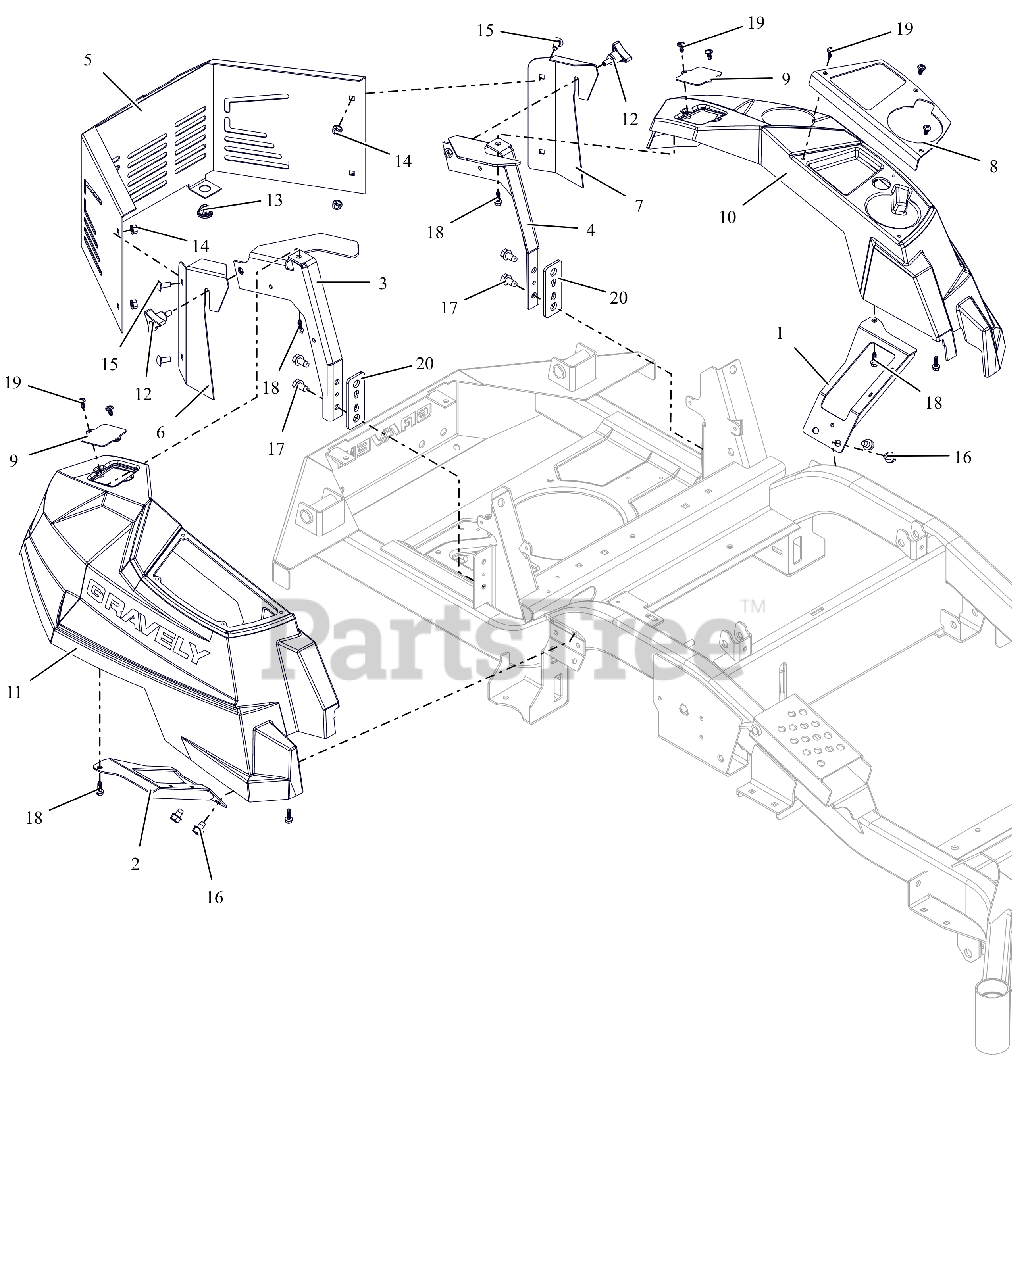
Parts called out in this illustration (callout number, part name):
1	WLDMT, LH FENDER MOUNT
2	WLDMT, RH FENDER MOUNT
3	BRKT, RH FENDER MTG
4	BRKT, LH FENDER MTG
5	GUARD, HD ENGINE
6	TRIM, HOOD STYLE (RIGHT)
7	TRIM, HOOD STYLE (LEFT)
8	PANEL, HD
9	PLATE, ROPS HOLE-HD
10	KIT, FENDER W/FUEL DECAL-HD
11	FENDER, RH HD (2017) SHRT BOSS
12	KNOB,WING STUD 5/16-18 X .75
13	GROMMET, 10MM BOLLHOFF
14	NUT-LK-TOP-FLG .312-18 GF ZCC
15	BLT, RHSSN.31-18X.750 G5 ZCC
16	SCR,TAP .375-16X.50 HWH TR ZCC
17	SCR,TAP .375-16X.75 HWH TR ZCC
18	SCR, PLASTITE-HWH 0.25 X 0.75 ZC120
19	SCR-PAN .25-15X.50 6L H/LZB500
20	PLATE, CONTROL PANEL SPACER
